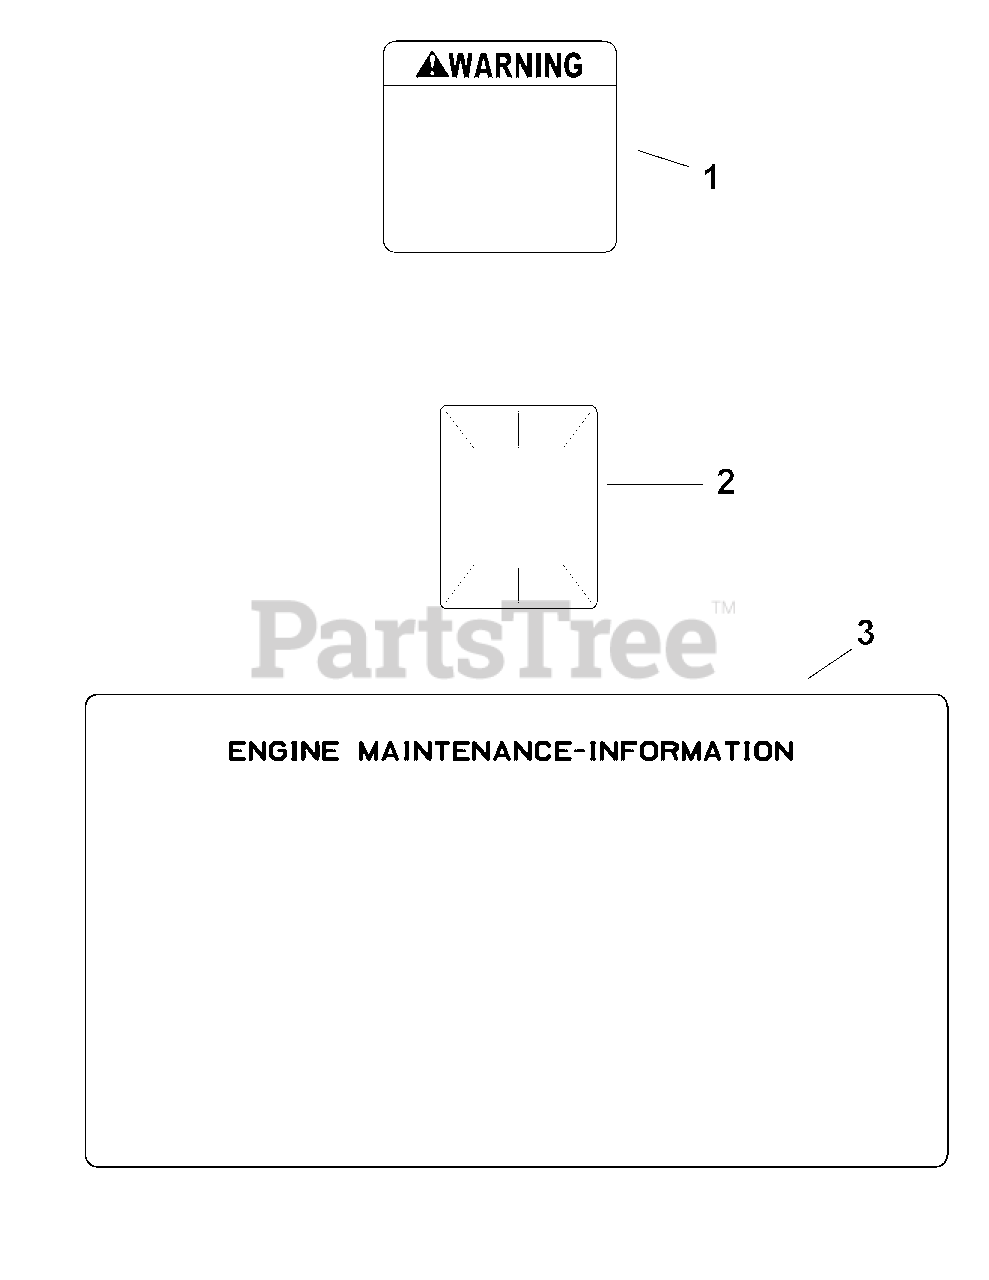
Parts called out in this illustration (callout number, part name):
1	DECAL, WARNING
2	DECAL, CLEAR LAMINATE
3	DECAL, ENGINE MAINT.
